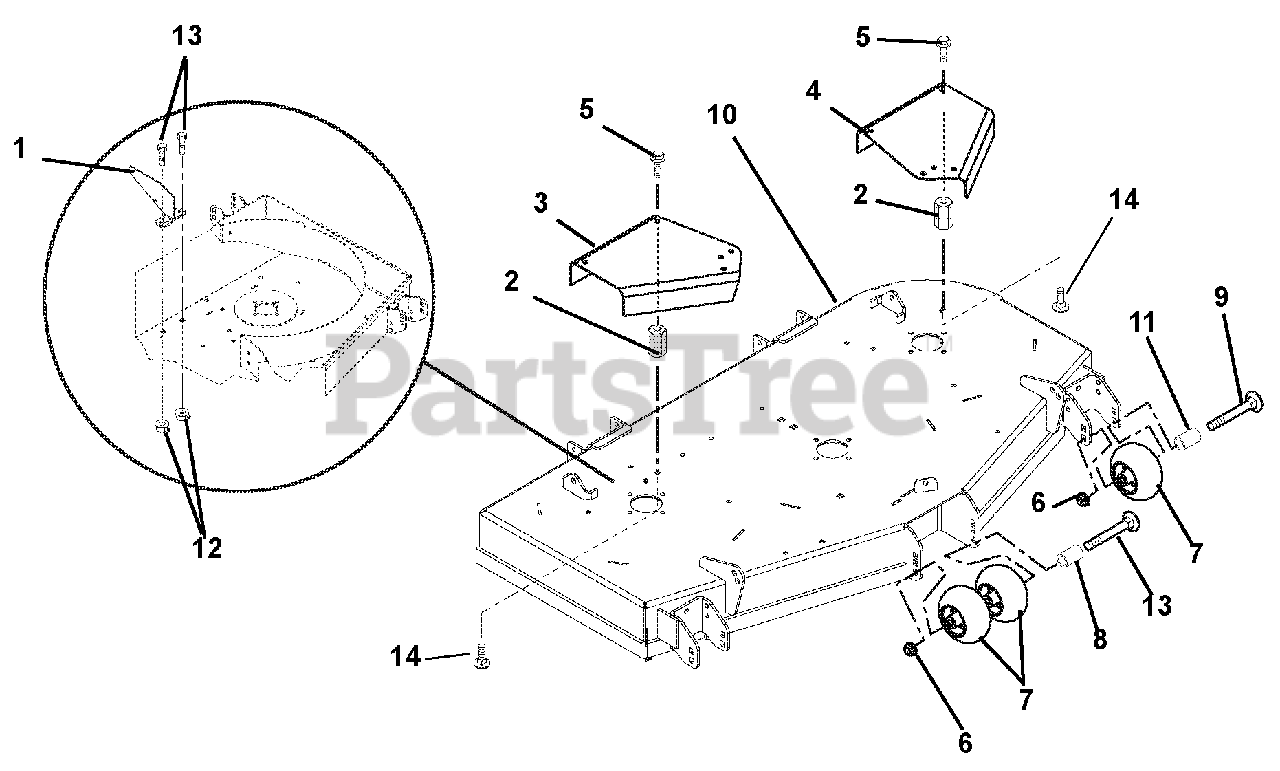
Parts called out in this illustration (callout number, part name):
1	Rear Deflector Baffle
2	Nut, Coupling, .31-18 x 3.00
3	52-in. Right Hand Spindle Guard (992322)
4	52-in. Left Hand Spindle Guard (992322)
5	Bolt, SEMS .31-18 x .62
6	Nut .50-13 Nyloc Flange
7	Anti-Scalp Wheel
9	Bolt-Round Head Square Neck .50-13 x 5.00
10	52-in. Mower Deck (992322)
11	Spacer, .510 x .625 x 3.35
12	Nut, .38-16 Nyloc Flange
13	Bolt, Round Head Square Neck, 3/8-16 x 1.00
14	Bolt, Round Head Square Neck, .31-18 x .75 Loc-Tite®
